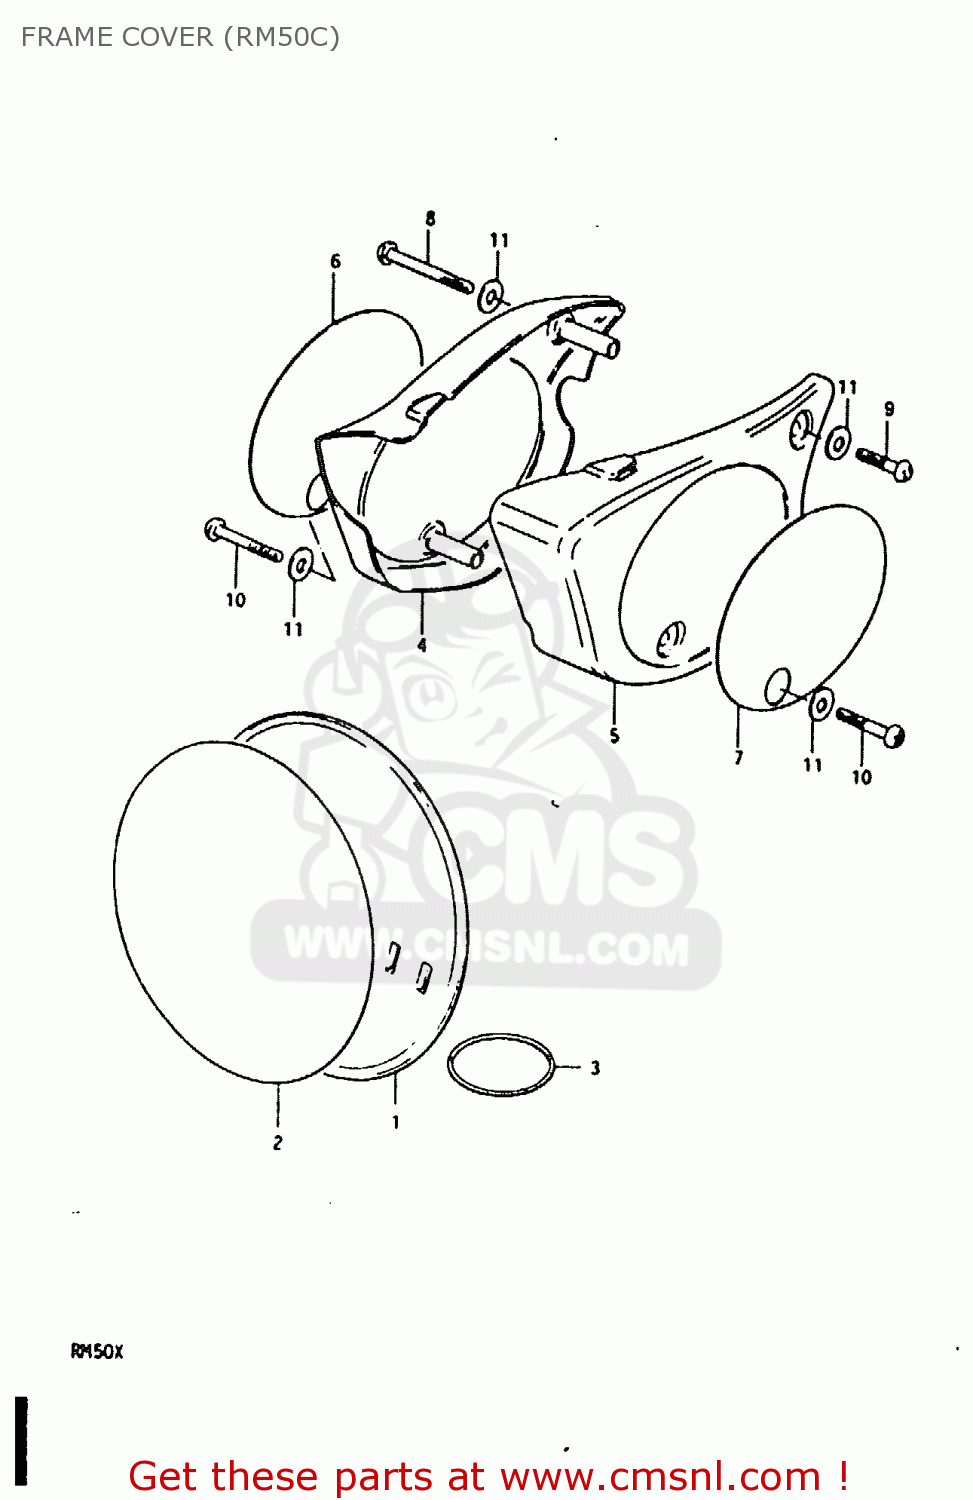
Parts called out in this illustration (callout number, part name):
1	PLATE,NUMBER,FRONT
2	EMBLEM,FRONT NUMBER PLATE
3	O-RING
4	COVER,FRAME,RIGHT
5	COVER,FRAME,LEFT
6	TAPE,FRAME COVER
7	TAPE,FRAME COVER
8	SCREW
9	SCREW
10	SCREW
11	WASHER
